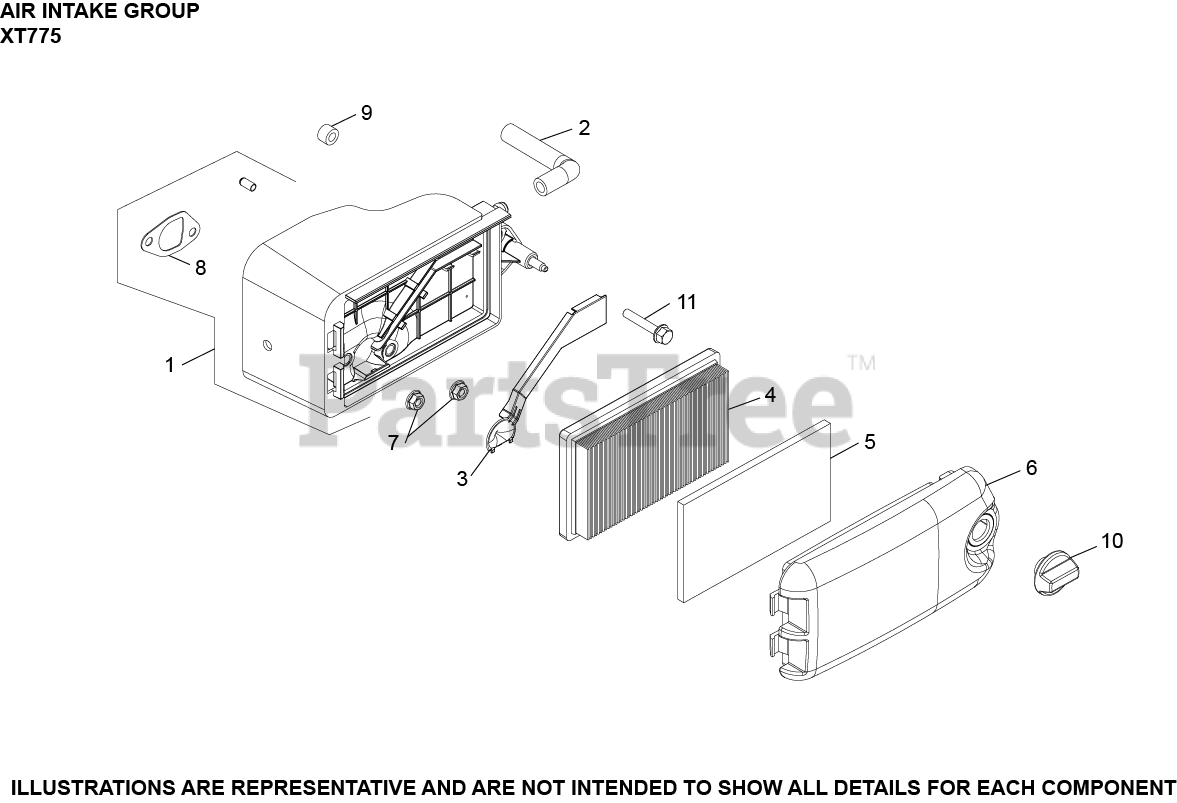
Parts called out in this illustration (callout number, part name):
1	BASE, AIR CLEANER
2	HOSE, BREATHER
3	COVER, A/C BASE (BREATHER GAS)
4	ELEMENT, AIR FILTER
5	ELEMENT, PRE-CLEANER
6	COVER, AIR CLEANER
7	NUT, HEX FLANGE (M6)
8	KIT, INTAKE GASKET
9	SPACER, AIR CLEANER BASE
10	KNOB, AIR CLEANER
11	SCREW, HEX FLANGE (M6)
